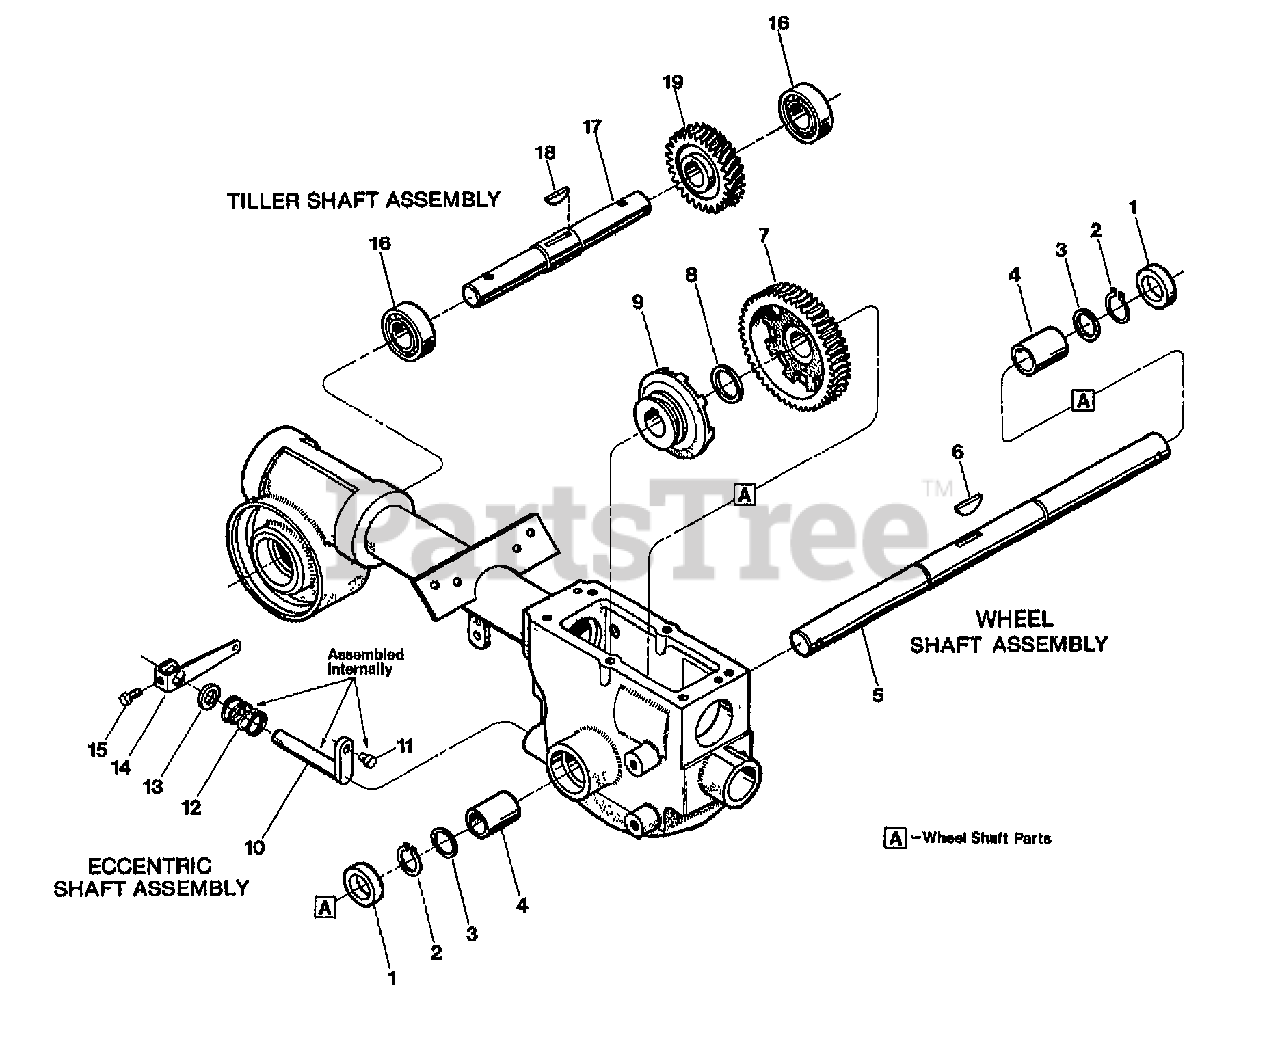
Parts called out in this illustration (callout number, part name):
1	SEAL-OIL WHEELSHAFT
2	RING-HEAVY EXT .906 ID
3	SHIM-1.375X1.015X.062
4	BUSHING-1.25X1.005X1.5
5	WHEELSHAFT W/KEY (AXLE)(INCL.#6)
6	KEY-HI PRO .25X1.312
7	GEAR-WORM 46 TEETH MACH
8	WASHER-1.468X1.016X.062
9	CLUTCH-MACH
10	WELD-ECCENTRIC
11	PIN-.375 X .72
12	SPRING-.850 X .875 LONG
13	SEAL-OIL ECCENTRIC
14	LEVER-CABLE ADJ PNT
15	SCR-HH 1/4-20X.5 GR5 YEL
16	BEARING-BALL
17	SHAFT-W/KEY (TILLER)
18	KEY-WOODRUFF .25X1.12
19	GEAR-TILLER MACH
